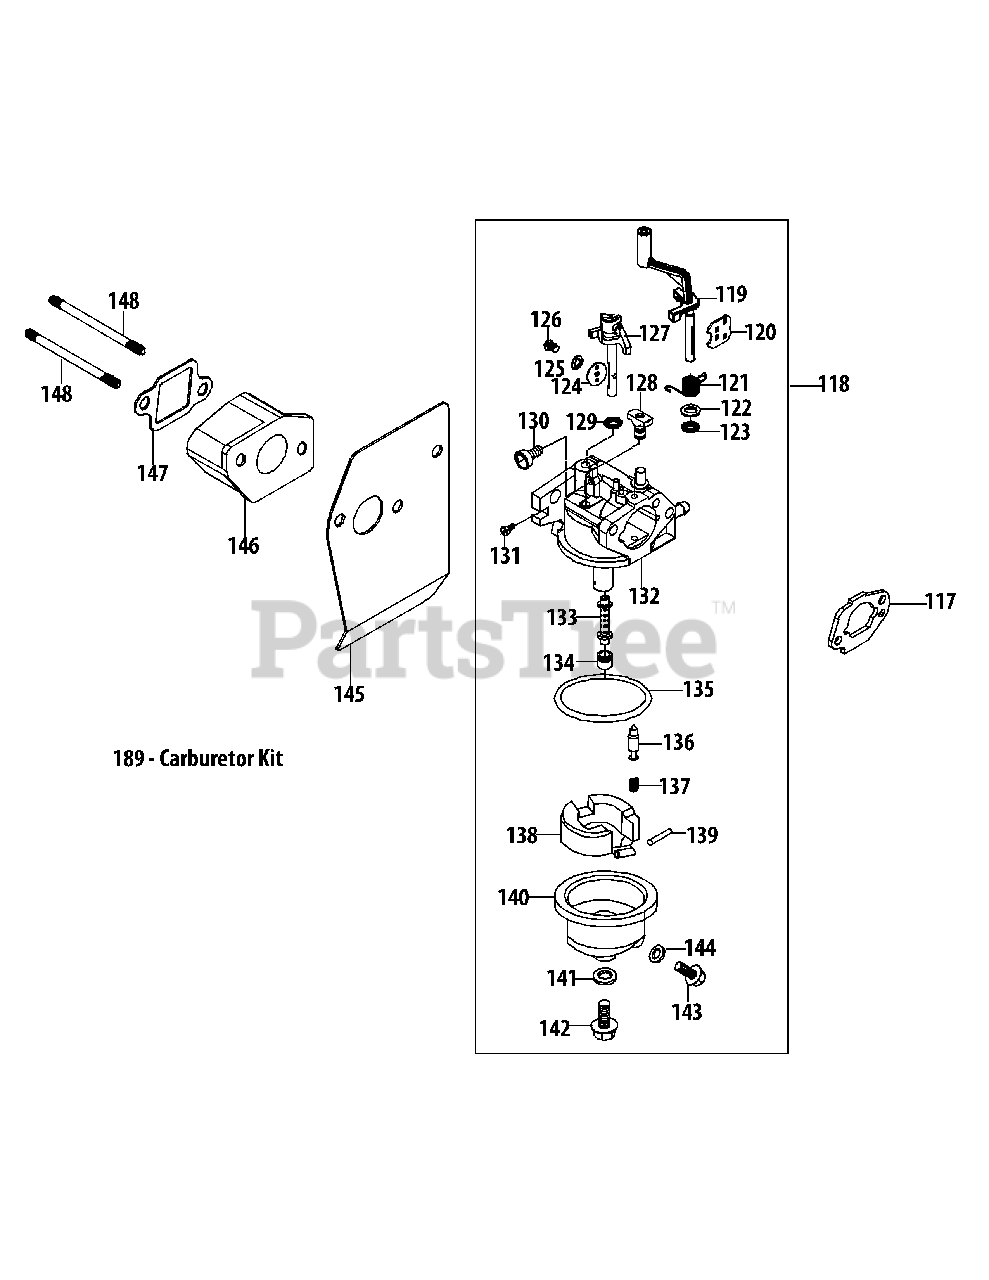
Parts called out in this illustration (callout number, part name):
117	Carburetor Gasket Plate
118	Carburetor Assembly
119	Choke Shaft
120	Choke Plate
121	Choke Return Spring
122	Choke Shaft Washer
123	Choke Shaft Fiber O-Ring
124	Throttle Plate
125	Throttle Plate Lock Washer
126	Screw M3X5 Throttle Plate
127	Throttle Shaft
128	Idle Jet Assembly
129	Throttle Shaft Fiber O-Ring
130	Idle Speed Adjusting Screw
131	Idle Mixture Screw
132	Carburetor Body
133	Emulsion Tube
134	Main Jet
135	Fuel Bowl O-Ring
136	Needle Valve
137	Needle Valve Spring
138	Float
139	Float Pin
140	Fuel Bowl
141	Fuel Bowl Gasket
142	Fuel Bowl Mounting Bolt
143	Fuel Drain Plug
144	Fuel Drain Plug Gasket
145	Carburetor Gasket
146	Carburetor Insulator
147	Carburetor Insulator Gasket
148	Carb Stud M6X113
189	Carburetor Repair Kit - Major
